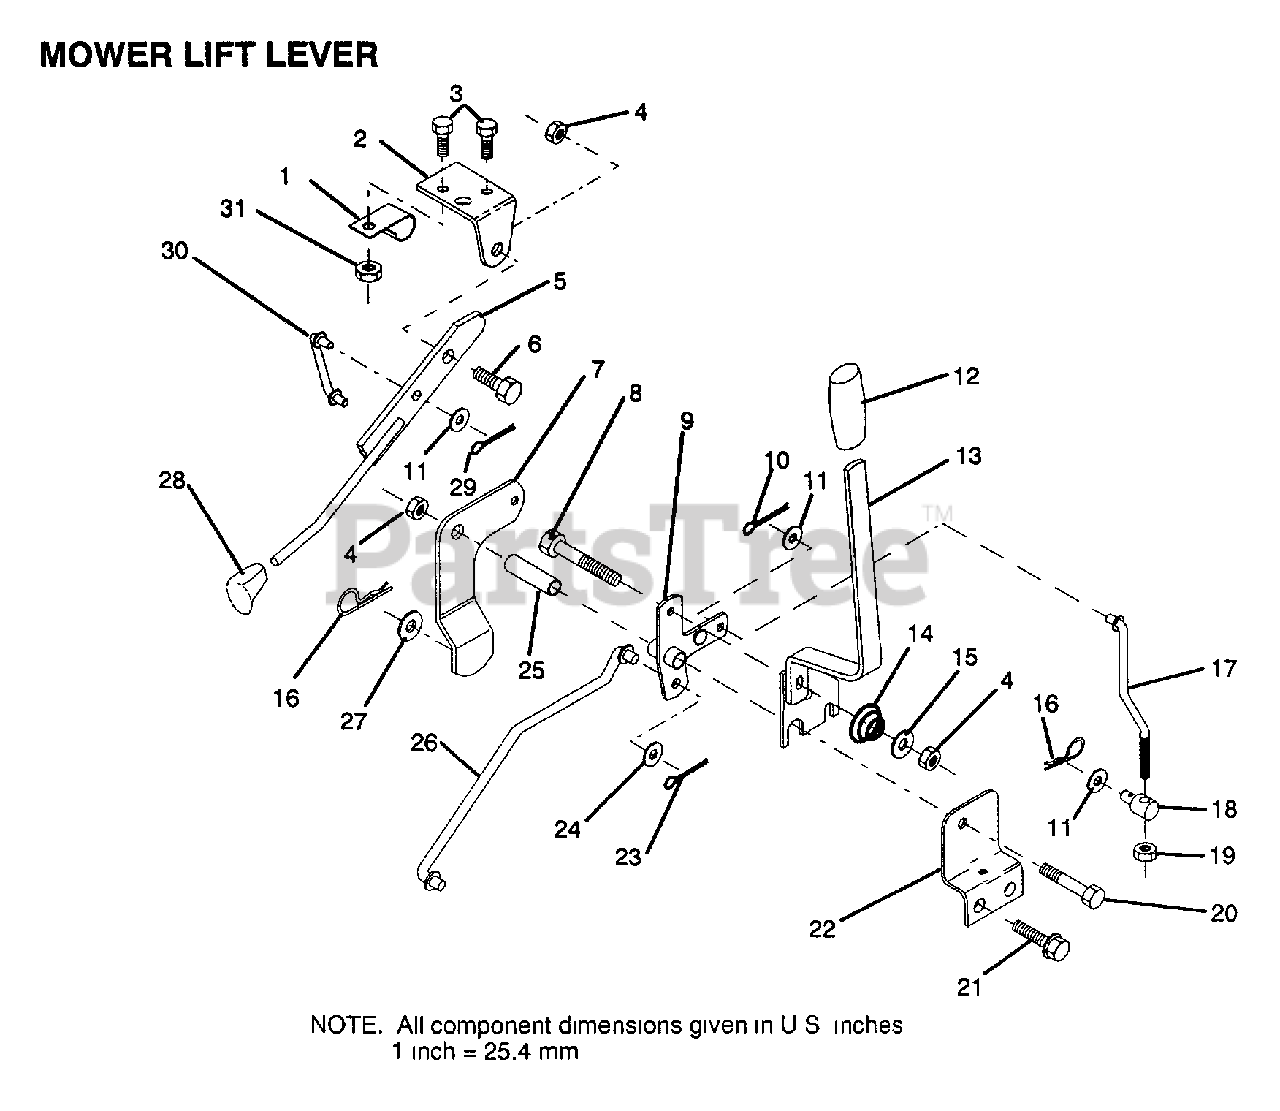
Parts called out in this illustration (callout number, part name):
1	"CLIP,INSULATOR"
2	BRKT CLUTCH
3	BOLT
5	CLUTCH LEVER AS
6	"BOLT, SHOULDER LT"
7	CLUTCH ARM ASS'Y
8	BOLT
9	"BELLCRANK,LIFT"
10	COTTER PIN
11	WASHER
12	GRIP HANDLE
13	"HDLE,LIFT T"
14	SPRING COMPRESSIO
15	WASHER T
16	SPRING.RETAINER
17	LINK FRT LIFT
19	NUT
20	BOLT
21	SCREW LT
22	"BRKT,MOWER HGT"
23	PIN COTTER 1/8
25	TUBE SPACER
26	"ROD,MOWER LIFT "
27	WASHER
28	KNOB
30	"LINK,MOWER LIFT"
